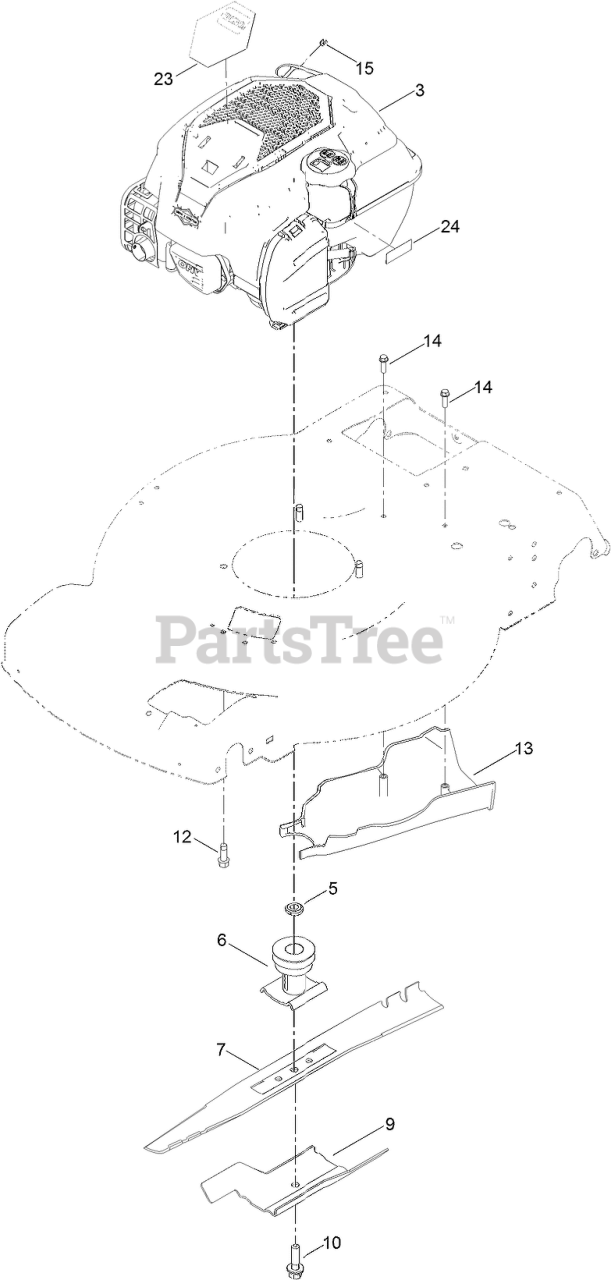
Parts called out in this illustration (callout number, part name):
5	Spacer-Driver
6	DRIVER-BLADE
9	Accelerator-Blade
10	BOLT-BLADE
12	SCREW-TAPTITE
13	COVER-BELT, REAR
14	SCREW-HWH
15	STOP-ROPE
23	DECAL-SHROUD
24	DECAL-LEVEL, FUEL
